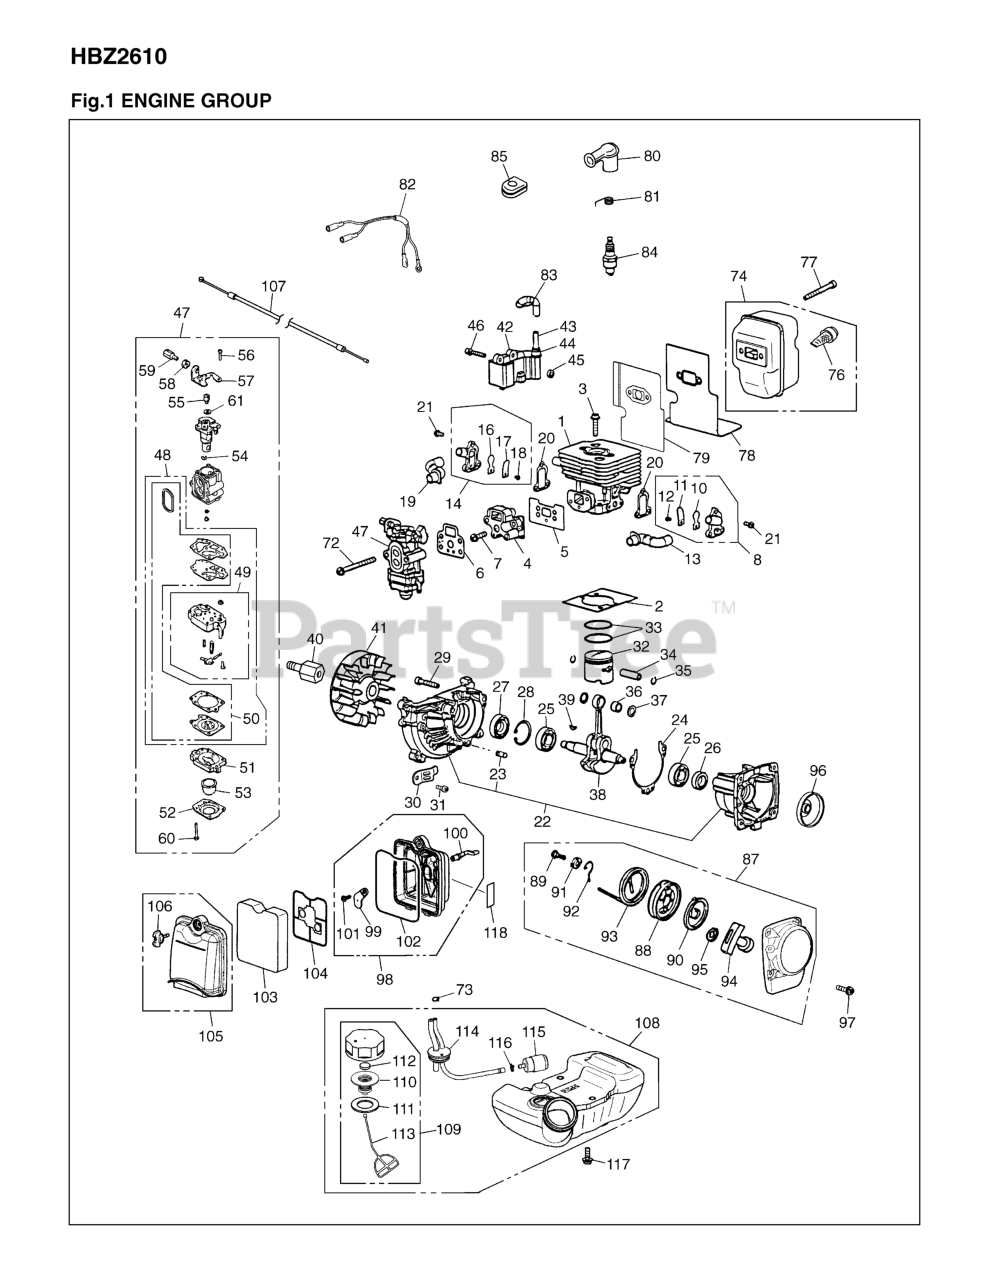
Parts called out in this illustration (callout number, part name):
1	CYLINDER
2	GASKET
3	BOLT
4	INSULATOR
5	GASKET INSULATOR
6	GASKET, CARB
7	BOLT (RPLS 2850-14220)
8	REEDVALVE ASSY (S)
13	PIPE, AIR S
14	REEDVALVE ASSY (F)
19	PIPE, AIR F
20	GASKET, VALVE
21	BOLT
22	CRANKCASE-C
23	PIN
24	GASKET
25	BEARING
26	SEAL
27	SEAL, OIL (RPLS 1140-21220)
28	RING, SNAP, M28 x 1.2
29	BOLT
31	BOLT
32	PISTON
33	RING
34	PIN
35	RING
36	BEARING
37	WASHER
38	CRANKSHAFT COMP
39	KEY
40	EXTENSION
41	ROTOR
42	COIL ASSY
43	CORD
44	CAP
45	SPACER
46	BOLT TORX
47	CARBURETOR ASSY
48	REBUILD KIT
49	BODY ASSY
50	GASKET KIT
51	BODY
52	COVER
53	PUMP
54	RING
55	SWIVEL
56	SCREW
58	NUT
59	SCREW
60	SCREW
61	WASHER
72	BOLT
73	CLIP
74	MUFFLER ASSY
76	ARRESTER
77	BOLT TORX
78	GASKET
79	PLATE
81	SPRING
82	CORD COMP
83	TUBE
84	SPARK PLUG
85	GROMMET
87	RECOIL ASSEMBLY
88	REEL
89	SCREW
90	SPRING
91	COLLAR
92	ARM
93	ROPE
94	KNOB
95	PLATE
96	PULLEY
97	BOLT
98	BODY A
99	PLATE, CHOKE
100	LEVER
101	SCREW
102	PACKING
103	ELEMENT
104	SCREEN (REPLACES -83K1)
105	COVER ASSY
106	KNOB
107	CABLE
108	TANK ASSY
109	CAP ASSY
110	HOLDER ASSY
111	PACKING
112	FILTER
113	STOPPER
114	PIPE COMP
115	FILTER ASSY
116	CLIP
117	BOLT TORX
118	LABEL
